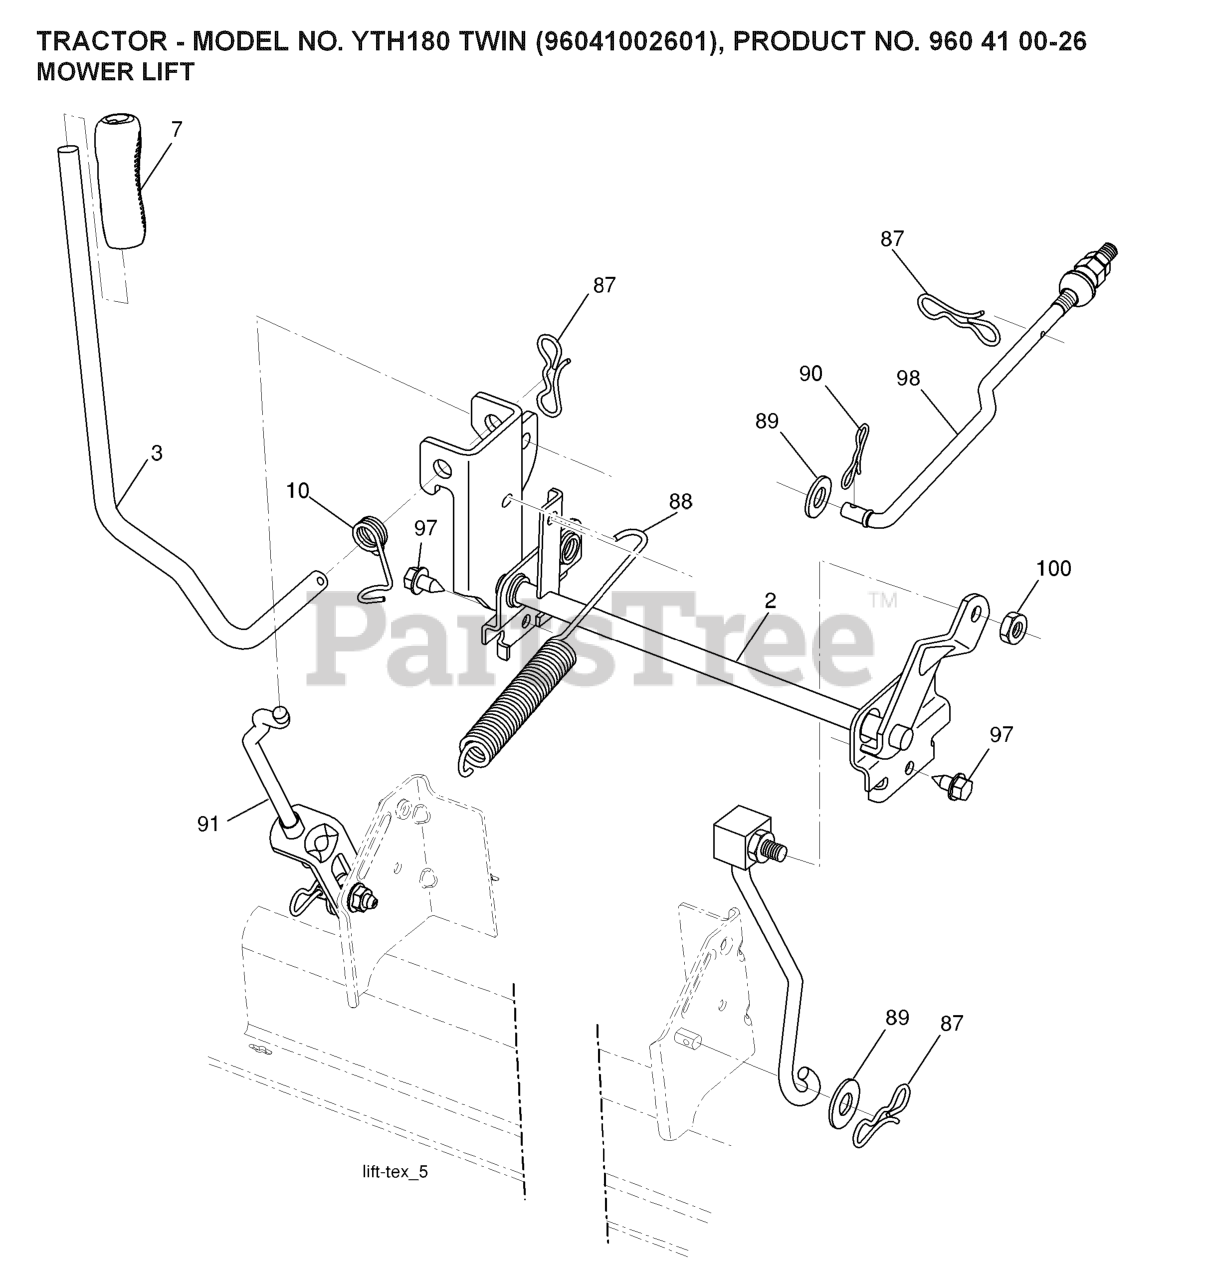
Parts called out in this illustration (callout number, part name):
2	SHAFT.ASM.LIFT.CROSS.H
3	LEVER.LIFT.HANDLE.GT
7	GRIP.HANDLE.LIFT.PVC.BLACK
10	SPRING.TORSION.LIFT.HANDLE
87	PIN.COTTER.7/16.BOW TI.
88	SPRING.LIFT.ASSIST.GT2
89	WASHER.CLEAR.ZINC
90	PIN.COTTER.5/16.BOW TI
91	LINK.ASM.LIFT.REAR
97	SCREW 3/8-16X3/4
98	LINK.ASM.SUSP.FRONT.MW
100	LOCKNUT
